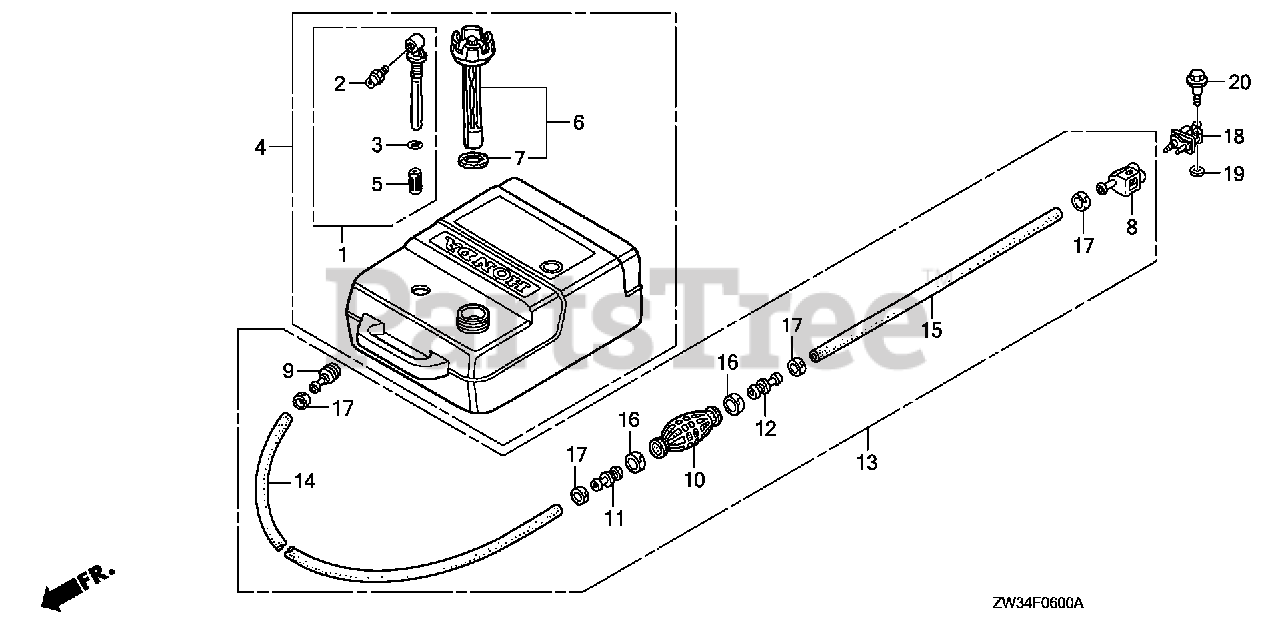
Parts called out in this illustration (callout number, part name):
8	CONNECTOR ASSY., FUEL (A)
9	CONNECTOR, FUEL (CONNECTOR TYPE)
10	BULB, PRIMER
11	VALVE, IN.
12	VALVE, OUTLET
13	TUBE ASSY., FUEL
14	TUBE, FUEL LONG (7.3X2000) (CONNECTOR TYPE)
15	TUBE, FUEL SHORT (6.3X500) (CONNECTOR TYPE)
16	BAND, TUBE CLIP (20MM)
17	BAND, TUBE CLIP (12.5MM)
18	CONNECTOR ASSY., FUEL (B)
19	WASHER, PIVOT
20	BOLT, SPECIAL (6X22) (CT200)
